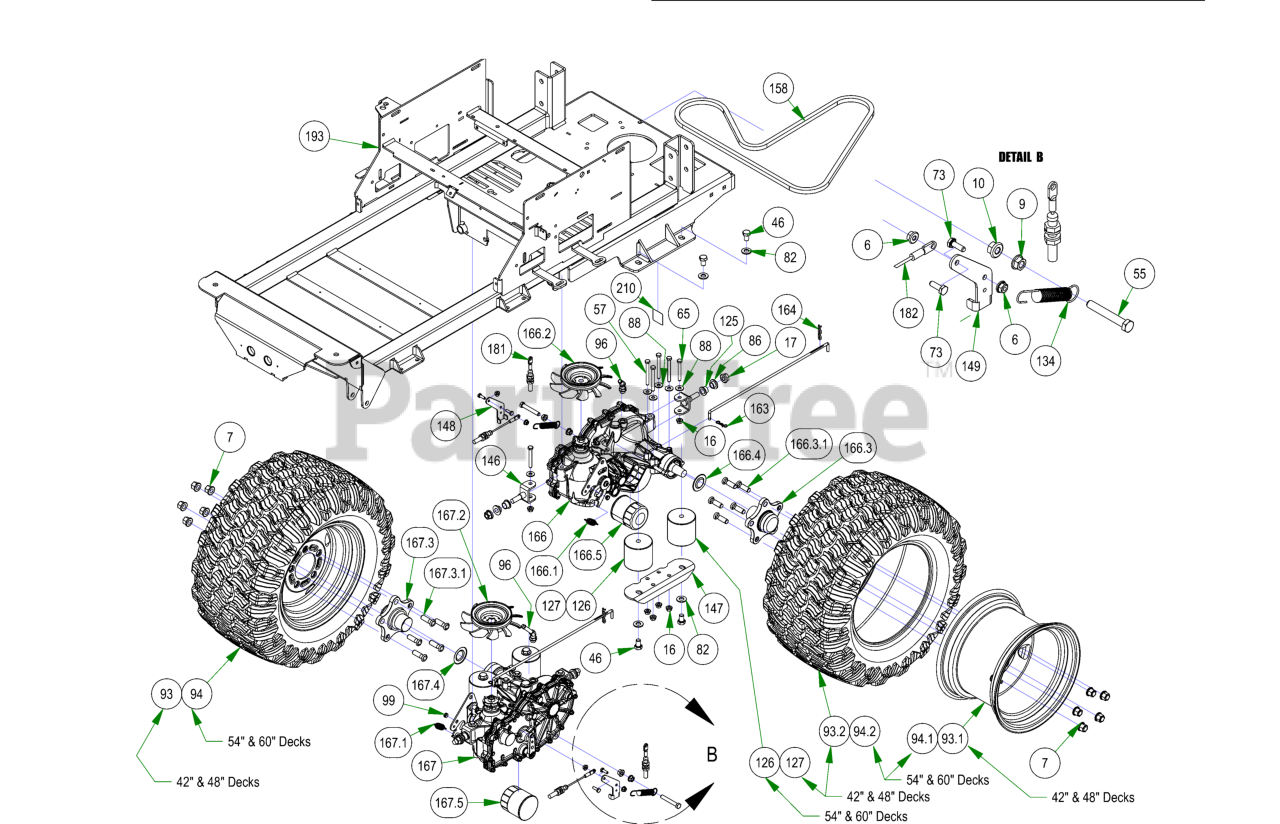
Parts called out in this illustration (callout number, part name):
6	1/4-20 NYL INSERT FLANGE LOCKNUT ZINC
7	Acorn Lug Nut
9	3/8-16 HEX SERRATED FLANGE NUT HARD/ZINC
10	3/8-16 NYLON INSERT FLANGE LOCKNUT (GR.F) ZINC
16	5/16-18 NYLON INSERT FLANGE LOCKNUT ZINC
17	1/2-13 NYLON INSERT FLANGE LOCKNUT ZINC
46	1/2-13 X 3/4 HEX CAP SCREW (GR.5) ZINC
55	3/8-16 X 2-1/2 HEX TAP BOLT (GR.5) ZINC Fully Threaded
57	5/16-18 X 3 HEX CAP SCREW (GR.5) ZINC
61	3/8-16 X 1 CARRIAGE BOLT (GR.5) ZINC
65	5/16-18 X 2-1/2 HEX CAP SCREW (GR.5) ZINC
73	1/4-20 X 3/4 HEX CAP SCREW (GR.5) ZINC
82	1/2 SAE FLAT WASHER (1-1/16" OD) GR.8 ZINC YELLOW
86	.525 ID SHOULDER WASHER NYLON
88	5/16 USS FLAT WASHER (7/8 OD) ZINC
93	23x9-12 Reaper Turf Tire & Wheel Assembly
93.1	12x7" Black Wheel
93.2	23x9-12 Reaper Turf Tire Only
94	23x11-12 Reaper Turf Assembly
94.1	12x8.5 Black Wheel
94.2	Tire, 23/11x12 Reaper Turf
96	ZT Fitting, 3/8 x 3/8 45 Degree, 4603-6-6
99	Drive Arm Transaxle Spacer
112	Neutral Rod
125	.627 ID X .753 OD X .500 LGTH X 1.000 FLG OD X .094 FLG THICK FLANGED BEARING OIL-IMPREG BRNZ
126	Vibration Mount-Green Dot
127	Vibration Mount- Red Dot
134	Brake Return Spring
146	Maverick Rear Transaxle Pivot Bracket
147	Rear Suspension Transaxle Mount
148	Brake Arm Ext (Left)
149	Brake Arm Ext (Right)
158	75.8" Pump Belt
164	Neutral Rod Clip
166	Compact Outlaw/Revolt Transaxle Left 3400
166.1	Gold Transaxle Spring
166.2	Fan/Pulley Kit for CZT Also for the 050-0075-01
166.3	5 Bolt Hub Kit
166.3.1	Transaxle Wheel Studs/ Drum Brake Studs
166.4	Seal Kit for 3400 Transaxle fits the 050-6000-01 / 050-6001-01
166.5	ZT Hydraulic Filter
167	Compact Outlaw/Revolt Transaxle Right 3400
167.1	Gold Transaxle Spring
167.2	Fan/Pulley Kit for CZT Also for the 050-0075-01
167.3	5 Bolt Hub Kit
167.3.1	Transaxle Wheel Studs/ Drum Brake Studs
167.4	Seal Kit for 3400 Transaxle fits the 050-6000-01 / 050-6001-01
167.5	ZT Hydraulic Filter
181	2021 Load Balanced Brake Cable 1
182	2021 Load Balanced Brake Cable 2
193	2022 Maverick Frame - Painted
210	Patent Decal
